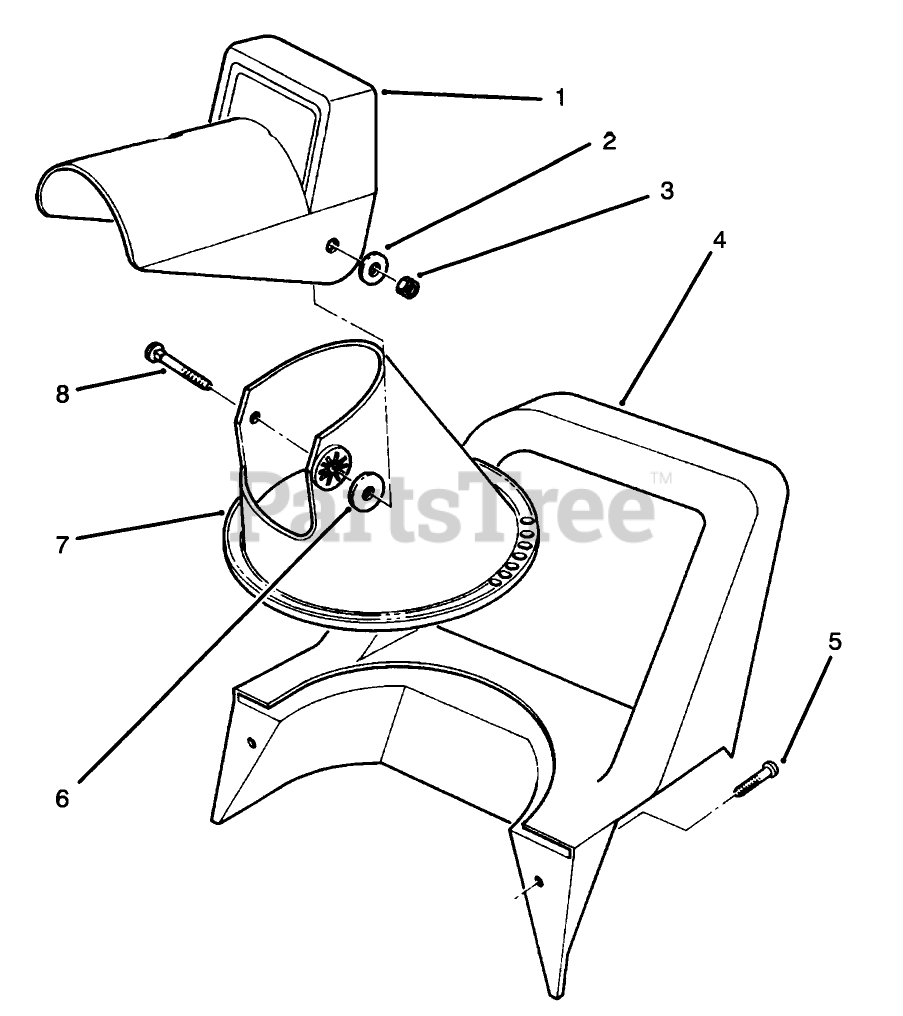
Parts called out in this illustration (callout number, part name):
1	CHUTE-DEFLECTOR
2	WASHER-FLAT
3	NUT-LOCK, NI
4	MIDDLE HANDLE - 1800
6	WASHER-RUBBER
7	LOWER CHUTE, 1800
8	BOLT-CARR
